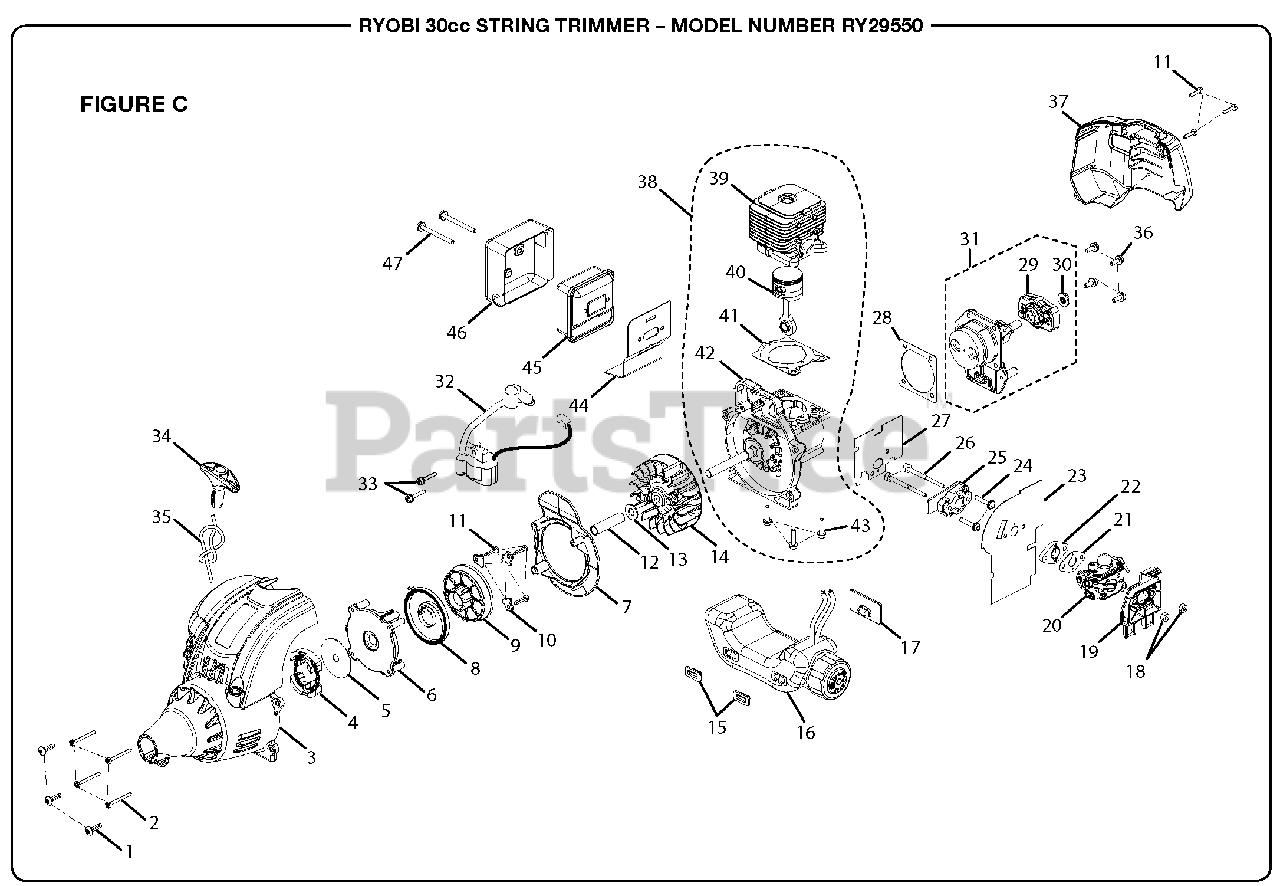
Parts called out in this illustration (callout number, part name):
1	Screw (10-24 x 3/4 in.)
2	Screw (M4 x 38 mm)
3	Starter Housing Assembly
4	Clutch Assembly
6	Starter Retaining
7	Baffle Plate
8	Spring & Container
10	Pulley Retainer
11	Screw (M4 x 18 mm)
13	Washer
14	Rotor Assembly
15	Bumper
16	Fuel Tank & Cap Assembly
18	Lock Nut (10-24)
19	Air Filter Base
20	Carburetor Assembly
21	Carburetor Gasket
22	Gasket
23	Carburetor Gasket
24	Screw (10-24 x 1 in. Pan Hd.)
26	Screw (10 x 2-1/2 in.)
27	Heat Dam Gasket
28	Crankcase Gasket
29	Pulley Assembly
30	Nut (M8 x 1-1/4 in.)
31	Crankcase Cover Assembly
33	Screw (M4 x 25 mm)
34	Starter Grip
35	Starter Rope
36	Screw (10-24 x 3/4 in. Pan Hd.)
37	Rear Housing
38	Short Block Assembly (Inc. Key Nos. 39-43)
39	Cylinder
40	Piston w/Rod Assembly
41	Cylinder Gasket
42	Crankcase Assembly
43	Screw (M5 x 20 mm)
44	Muffler Gasket
45	Muffler Assembly
46	Heat Shield
47	Screw (10-24 x 2-1/8 in.)
